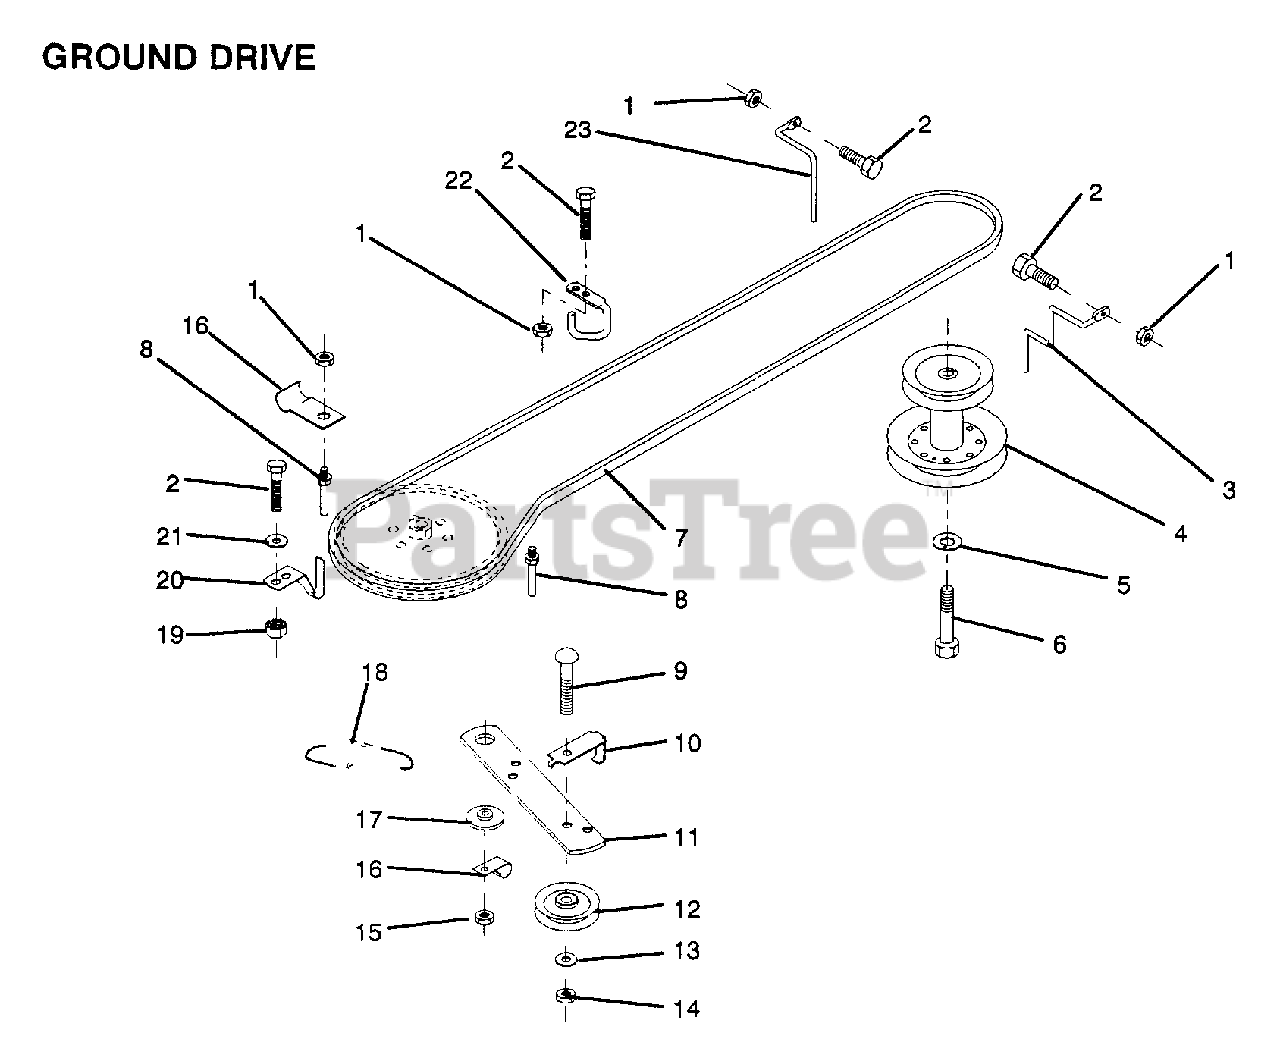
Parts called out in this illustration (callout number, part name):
2	BOLT
3	KEEPER ENG BEL LH
5	LOCKWASHER
6	BOLT
7	V BELT
8	"KEEPER,DRIVE BELT"
9	BOLT
10	"KEEP,IDLER DR BEL"
12	PULLEY.IDLER.FLAT
13	WASHER
14	LOCKNUT
16	"CLIP,INSULATOR"
17	SPACER RETAINER
20	"KEEPER,DR BELT "
21	WASHER
22	"KEEPER,FRA DR BEL"
23	KEEPER ENG DR RH
